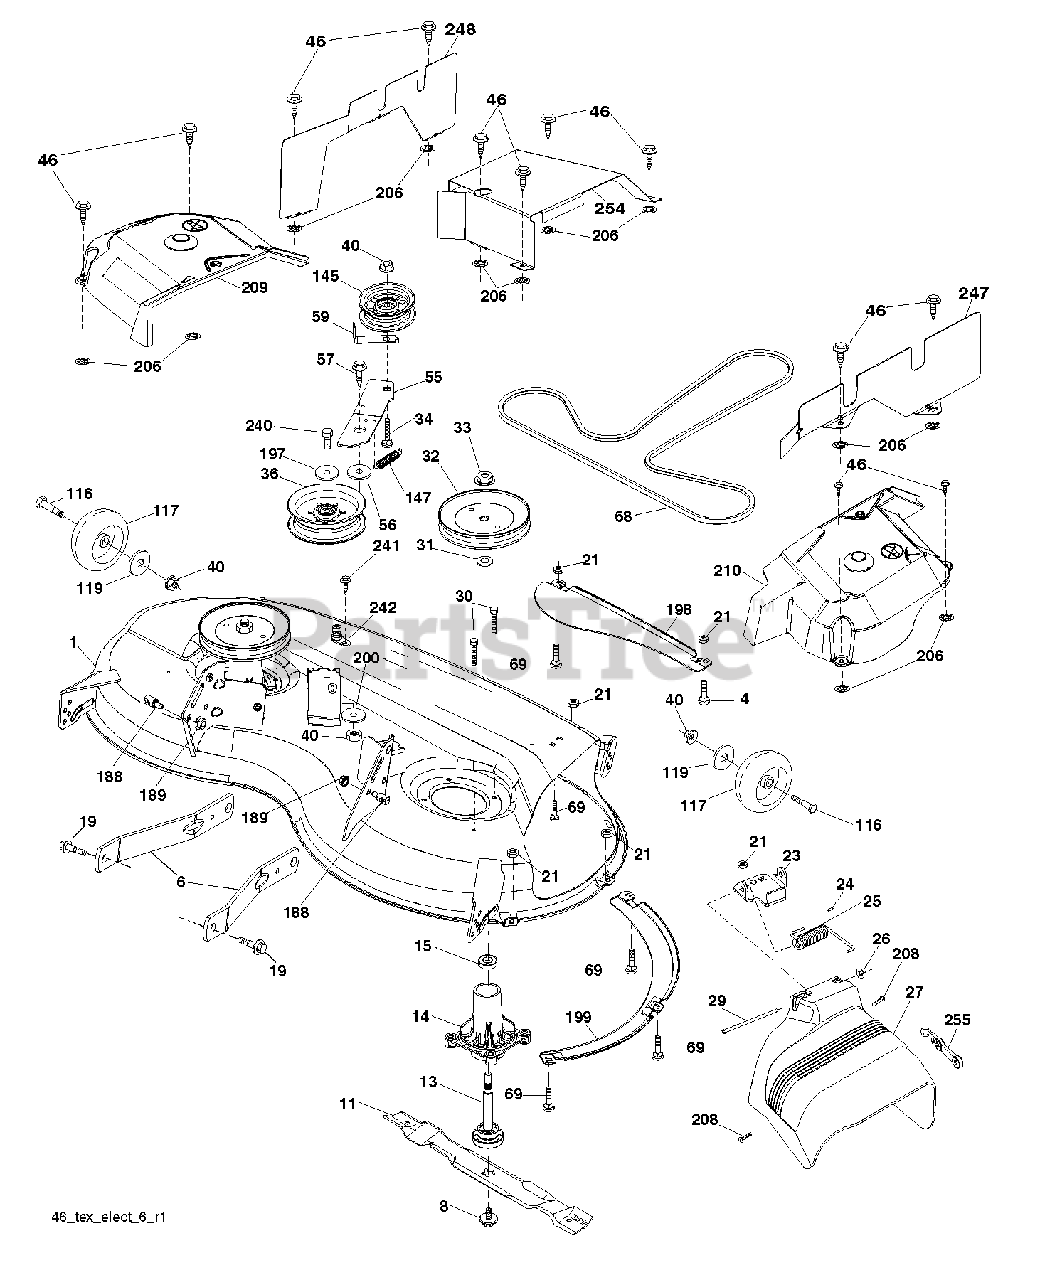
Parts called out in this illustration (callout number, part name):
4	BOLT
6	ARM.SUSPENSION.MOWER.R
8	BOLT.WASHER.ASM.7/16-2
11	BLADE 46" HI LIFT
13	SHAFT.ASM.MDRL.N/GREASE.38
14	HOUSING MANDREL
19	BOLT.SHOULDER
21	LOCKNUT
23	BRKT.DEFLECTOR.38"2005+
24	CAP-SLEEVE LT
25	SPRING.TORSION.DEFLECT
26	NUT PUSH M
29	ROD.HINGE
30	SCREW, WASHER HEAD
31	WASHER.SPACER.MANDREL
32	PULLEY.MANDREL.5.438.PD
33	NUT.FLANGE.LOCK.TOP
34	BOLT.3/8-16X1.50
36	PULLEY.IDLER.2006
40	NUT LOCK FLG 3/8-16 UNC
46	SCREW.1/4-20X5/8
55	IDLER.ARM
56	SPACER.RETAINER
57	SCREW 3/8-16X1
59	GUARD, BELT
68	V BELT
69	BOLT
116	BOLT.SHOULDER.3/8-16X3-5/8
117	WHEEL. GUAGE RALLY
145	PULLEY.IDLER.48"PRIMARY
147	SPRING.MOWER.DRIVE.ELECTRIC
188	STUD.FASTNER.W/ANTI-ROTATE
189	NUT LOCK HEX FLANGE 5/16-18
197	WASHER
198	BAFFLE CENTER FRONT
199	BAFFLE FRONT RH
200	WASHER.13/32 X 1 X 1/2.11GUARD
206	PALNUT 1/4
208	SCREW 3/8-16X1/2
240	BOLT-HEX EAK
242	PORT.WASHOUT
